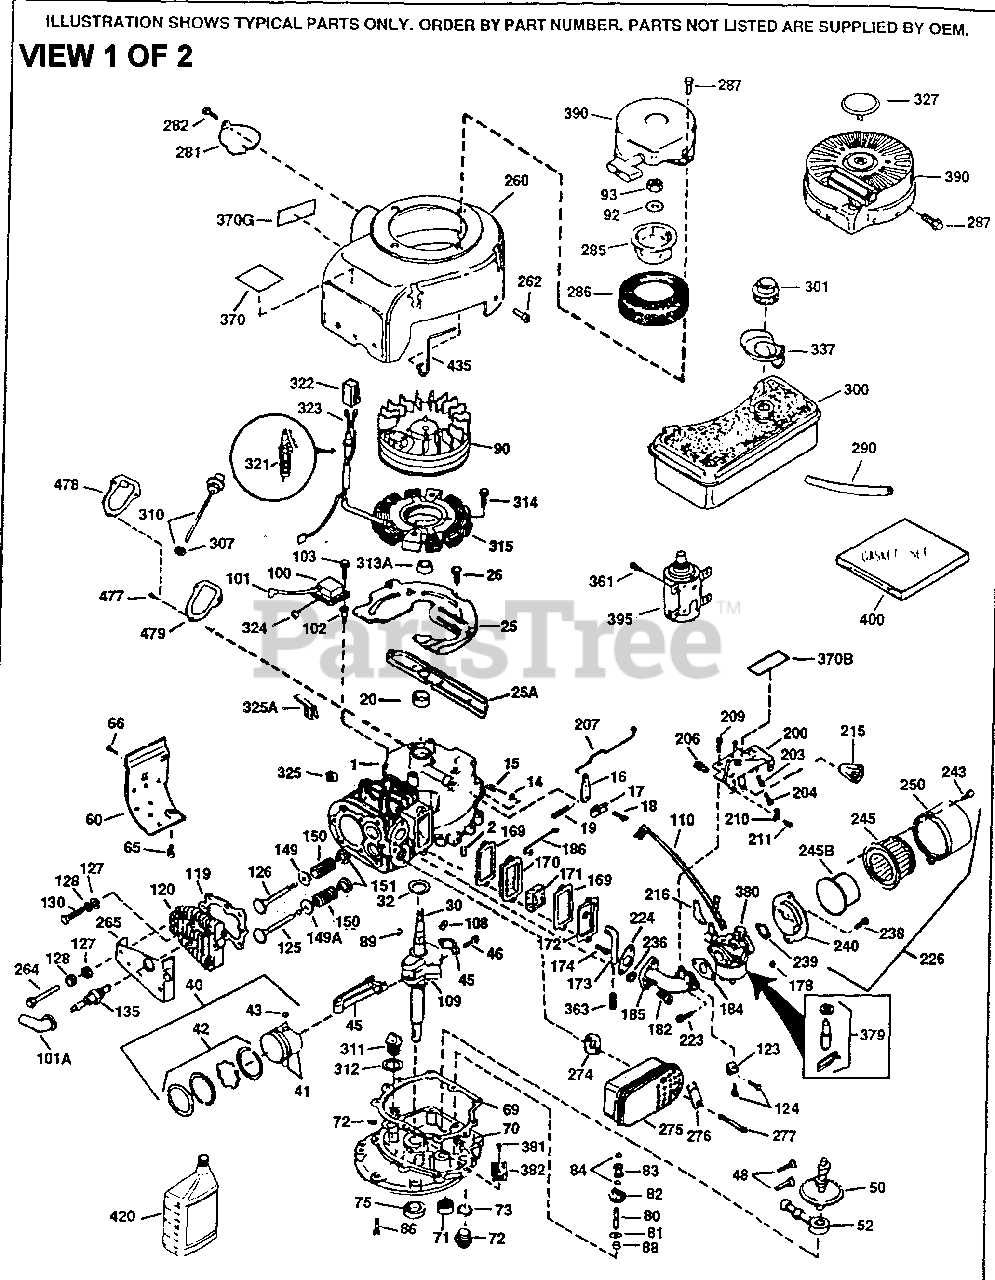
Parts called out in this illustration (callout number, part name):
1	"Cylinder (Incl. 2 & 20)
2	Dowel Pin
14	Flat Washer
15	Governor Rod (Incl. 14)
16	Governor Lever
17	Governor Lever Clamp
18	Screw, 8-32 x 5/16"
19	Extension Spring
20	Oil Seal
25	Blower Housing Baffle
26	Screw, 1/4-20 x 5/8"
30	Crankshaft
40	Piston, Pin & Ring Set (Std.)
40	Piston, Pin & Ring Set (.010" OS)
40	Piston, Pin & Ring Set (.020" OS)
41	Piston & Pin Ass'y. (Std.) (Incl. 43)
41	Piston & Pin Ass'y. (.010" OS) Incl. 43
41	Piston & Pin Ass'y. (.020" OS) Incl. 43
42	Ring Set (Std.)
42	Ring Set (.010" OS)
42	Ring Set (.020" OS)
43	Piston Pin Retaining Ring
45	Connecting Rod Ass'y. (Incl. 46)
46	Connecting Rod Bolt
48	Valve Lifter
50	Camshaft (MCR)
52	Oil Pump Ass'y.
60	Blower Housing Extension
65	Screw, 10-24 x 1/2"
66	Screw, T-30, 1/4-20 x 1/2"
69	* Mounting Flange Gasket
70	Mounting Flange (Incl. 72,75,80 & 81)
72	Oil Drain Plug (Sq. hd., 1/4-18)
75	Oil Seal
80	Governor Shaft
82	Governor Gear Ass'y. (Incl. 81)
83	Governor Spool
84	Retaining Ring
86	Screw, 1/4-20 x 1-1/4"
88	Spacer (Incl. 81)
89	Flywheel Key
90	Flywheel
92	Belleville Washer
93	Flywheel Nut
100	Solid State Ignition
101	Spark Plug Cover
102	Solid State Mounting Stud
103	Screw, Torx T-15, 10-24 x 15/16"
110	Ground Wire (One female, One eyelet)
119	* Cylinder Head Gasket
120	Cylinder Head
125	Exhaust Valve (Std.)(Incl. 151)
125	Exhaust Valve (1/32" OS) (Incl. 151)
126	Intake Valve (Std.) (Incl. 151)
126	Intake Valve (1/32" OS) (Incl. 151)
128	Belleville Washer
130	Screw, 5/16-18 x 2-1/2"
135	Resistor Spark Plug - RJ17LM
149	Valve Spring Cap
150	Valve Spring
151	Valve Spring Keeper
169	* Valve Cover Gasket
170	Breather Body
171	Breather Element
172	Valve Cover
173	Breather Tube
174	Screw, 10-24 x 1/2"
178	Screw, 1/4-20 x 27/32"
182	Screw, Torx T-30, 5/16-18 x 1-1/8"
184	* Carburetor To Intake Pipe Gasket
185	Intake Pipe
186	Governor Link
200	Control Bracket (Incl. 203 & 204)
203	Compression Spring
204	Screw, 5-40 x 7/16"
207	Throttle Link
209	Screw, 10-24 x 9/16"
210	Conduit Clip
211	Screw, 10-32 x 3/8"
224	* Intake Pipe Gasket
238	Screw, 10-32 x 1/2"
239	* Air Cleaner Gasket
240	Air Cleaner Body
243	Screw, 8-32 x 3/8"
245	Air Filter (Paper) also available in Packaged Part #740029B
250	Air Cleaner Cover
260	Blower Housing
262	Screw, T-40, 5/16-24 x 21/32"
265	Cylinder Head Cover
274	* Exhaust Gasket
275	Muffler
276	Locking Plate
277	Screw, 5/16-18 x 2-3/4"
285	Starter Cup
287	Screw, 8-32 x 21/64"
290	Fuel Line (8.62")
300	Fuel Tank (Incl. 301)
301	Fuel Cap
307	"O" Ring
310	Dipstick
325	Wire Clip
327	Starter Plug
337	Fuel Deflector
370	Lubrication Decal
380	Carburetor (Incl. 184)
390	Rewind Starter (Note: This engine co uld have been built with 590732 start er. Refer to the design of the rope p ulley strength ribs for part identifi cat ion. Individual starter parts do not interchange.
400	* Gasket Set (Incl. items marked PK in notes) Incl. part #'s 26756 (1), 2727 2A (1), 27896A (2), 27915A (1), 29673 (1), 30684 (1), 31688A (1), 33629 (1 ), 34912 (1), 35865 (1), 36445 (1)
435	Hold Down Clamp
